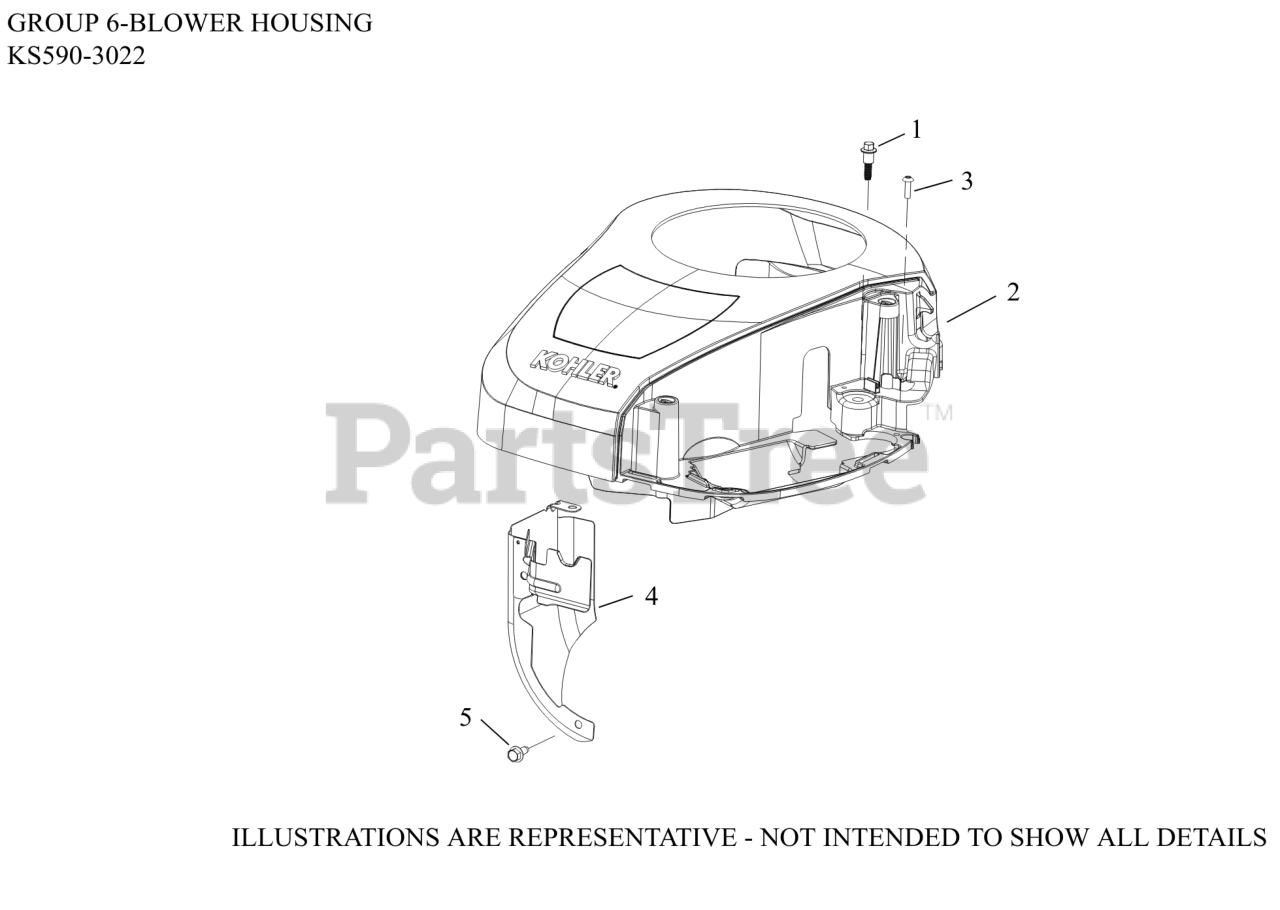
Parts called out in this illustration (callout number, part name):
1	SCREW, SHD THD FRM M6X1X26
2	KIT, BLOWER HOUSING
3	SCREW, HI-LOW
4	BAFFLE, BARREL ASSY
5	SCREW, THREAD FORMING
